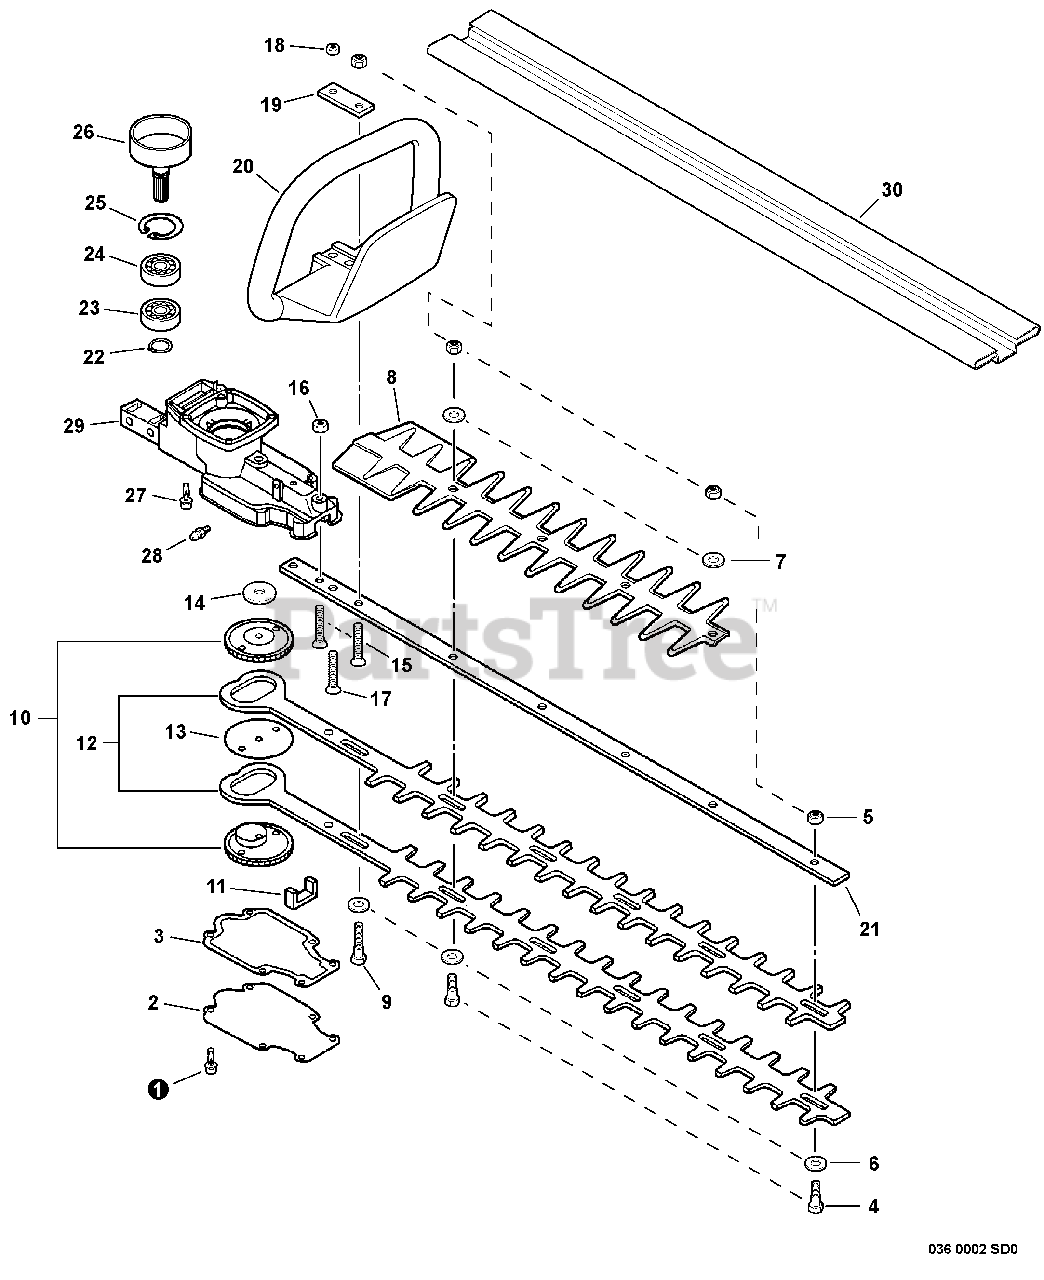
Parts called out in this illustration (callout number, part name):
1	SCREW - 4X12
2	LID, GEAR CASE
3	GASKET, GEAR CASE
4	BOLT - 6X18
5	LOCKNUT - 6
6	WASHER - 6
7	WASHER - 6
8	SHIELD, BLADE
9	BOLT - 6X35
10	GEAR - SPUR
11	SEAL, FELT
12	BLADE, TRIMMER
15	SCREW - 6X30
16	LOCKNUT - 6
17	SCREW - 5X30
18	LOCKNUT - 5
20	HANDLE - FRONT
21	SUPPORT, BLADE
22	RING, RETAINING - 14
23	BEARING, BALL - 6202
24	BEARING, BALL - 6202
25	RING, RETAINING - 35
26	DRUM, CLUTCH
27	SCREW - 4X16
28	FITTING, GREASE
29	CASE, GEAR
30	COVER, BLADE
